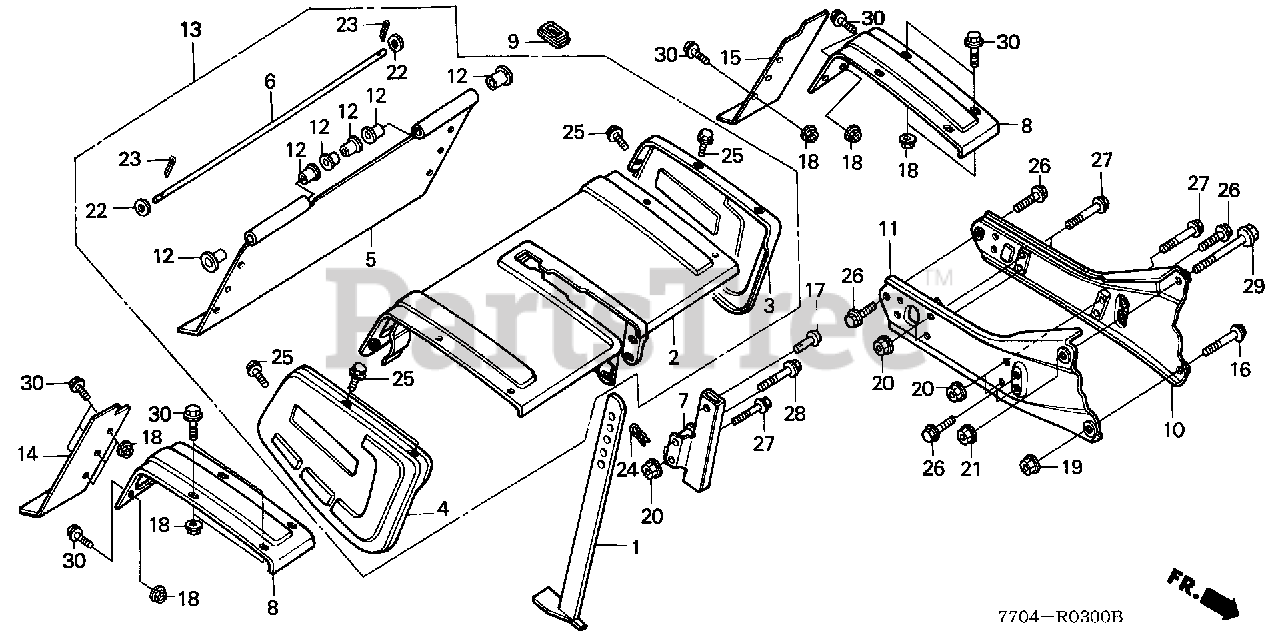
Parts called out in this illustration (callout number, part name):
1	BAR, DRAG *R280* (POWER RED)
2	COVER, ROTARY
3	COVER, L. ROTARY
4	COVER, R. ROTARY
5	SPLASH GUARD
6	SHAFT, SPLASH GUARD
7	HOLDER, DRAG BAR
8	COVER, ROTARY EXTENSION
9	GROMMET, ROTARY COVER
10	FRAME, L. ROTARY
11	FRAME, R. ROTARY
12	BUSH, DISCHARGE GUARD
13	COVER, ROTARY *R280* (POWER RED)
14	SPLASH GUARD, R. EXTENSION *R280* (POWER RED)
15	SPLASH GUARD, L. EXTENSION *R280* (POWER RED)
16	BOLT, HEX. (8X50)
17	PIN (10X30)
18	NUT, FLANGE (6MM)
19	NUT, FLANGE (8MM)
20	NUT, FLANGE (8MM)
21	NUT, FLANGE (10MM)
22	WASHER, PLAIN (6MM)
23	PIN, SPLIT (2.5X30)
24	PIN, LOCK (10MM)
25	BOLT, FLANGE (6X10)
26	BOLT, FLANGE (8X16)
27	BOLT, FLANGE (8X50)
28	BOLT, FLANGE (8X55)
29	BOLT, FLANGE (10X105)
30	BOLT, FLANGE (6X10)
